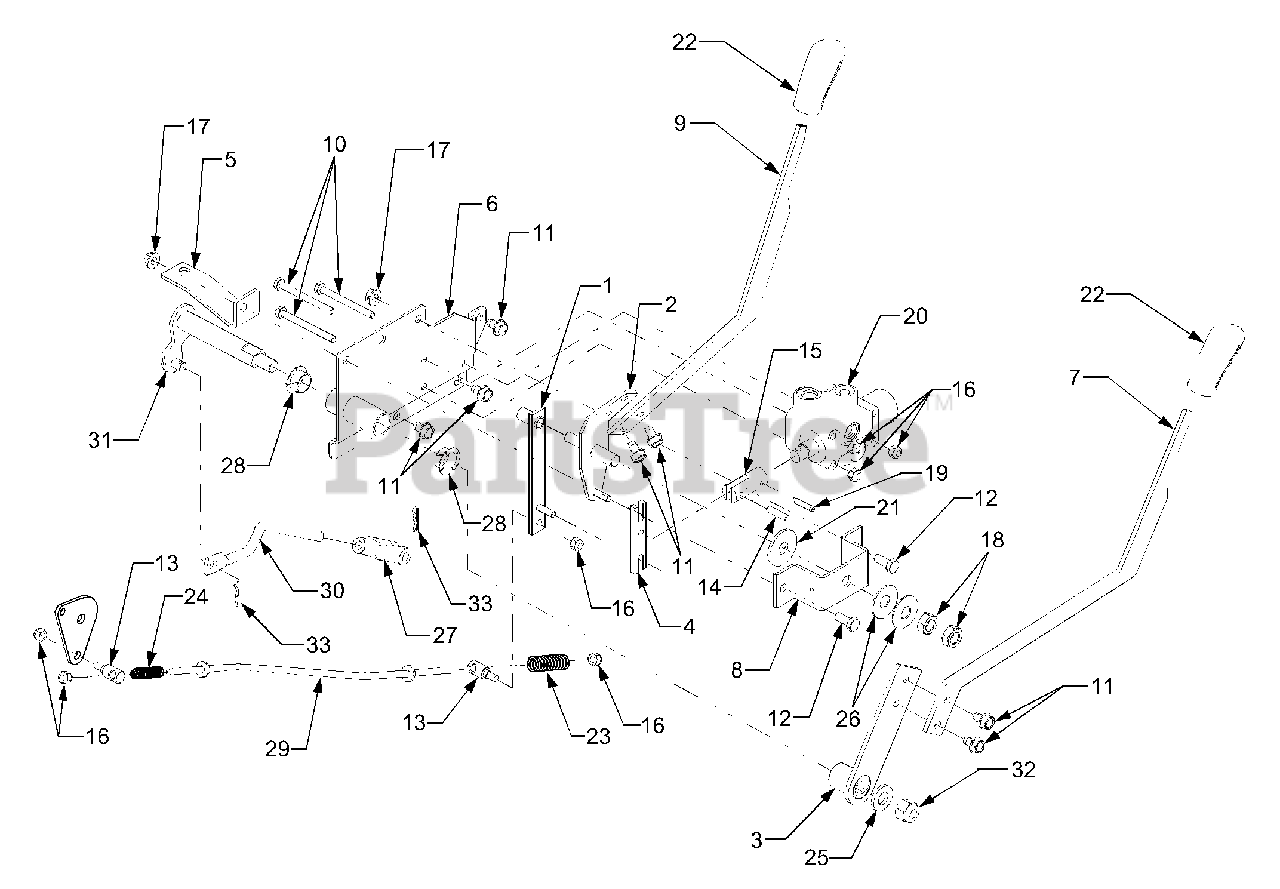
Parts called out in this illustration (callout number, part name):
1	Link Assembly, Feedback
2	Link Assembly, Input
3	Link, HI-LO Shifter
4	Link, Feedback
5	Bracket, Lift Brace
6	Bracket, Valve Mtg.
7	Handle, HI-LO Shifter
8	Bracket, Lift Mtg.
9	Handle, Lift
10	Screw, Hex Cap, 1/4-20 x 2.75 GR5
11	Screw, Hex Wash Hd. Tapp 5/16-18 x .5
12	Screw, Hex Cap, 5/16-18 x .75 GR5
13	Ferrule, Feedback Adjustment
14	Pin, .25 x 1.0
15	Link, Valve
16	Nut, Hex Nylon Insert Lock 14-20 GR8
17	Nut, Hex Flange Lock, 5/16-18 GR5
18	Nut, Hex Jam, 1/2-20 GR5
19	Pin, Spirol, 3/16 x 1.0
20	Valve, Hydaulic Lift
21	Washer, Friction, .515 x 1.5 x .12
22	Grip, Handle
23	Spring, Compression
24	Spring, Compression
25	Washer, Flat, .531 x 1.062 x .134
26	Washer, Belleville, .53 x 1.375 x .06
27	Clevis, Adjustment
28	Bearing, Nylon Flange .75 ID
29	Rod, Feedback
30	Rod, Hi-LO Connecting
31	Shaft, Hi-Lo Shifter
32	Nut, Hex Nylon Lock, 1/2-20
33	Pin, Internal Cotter
